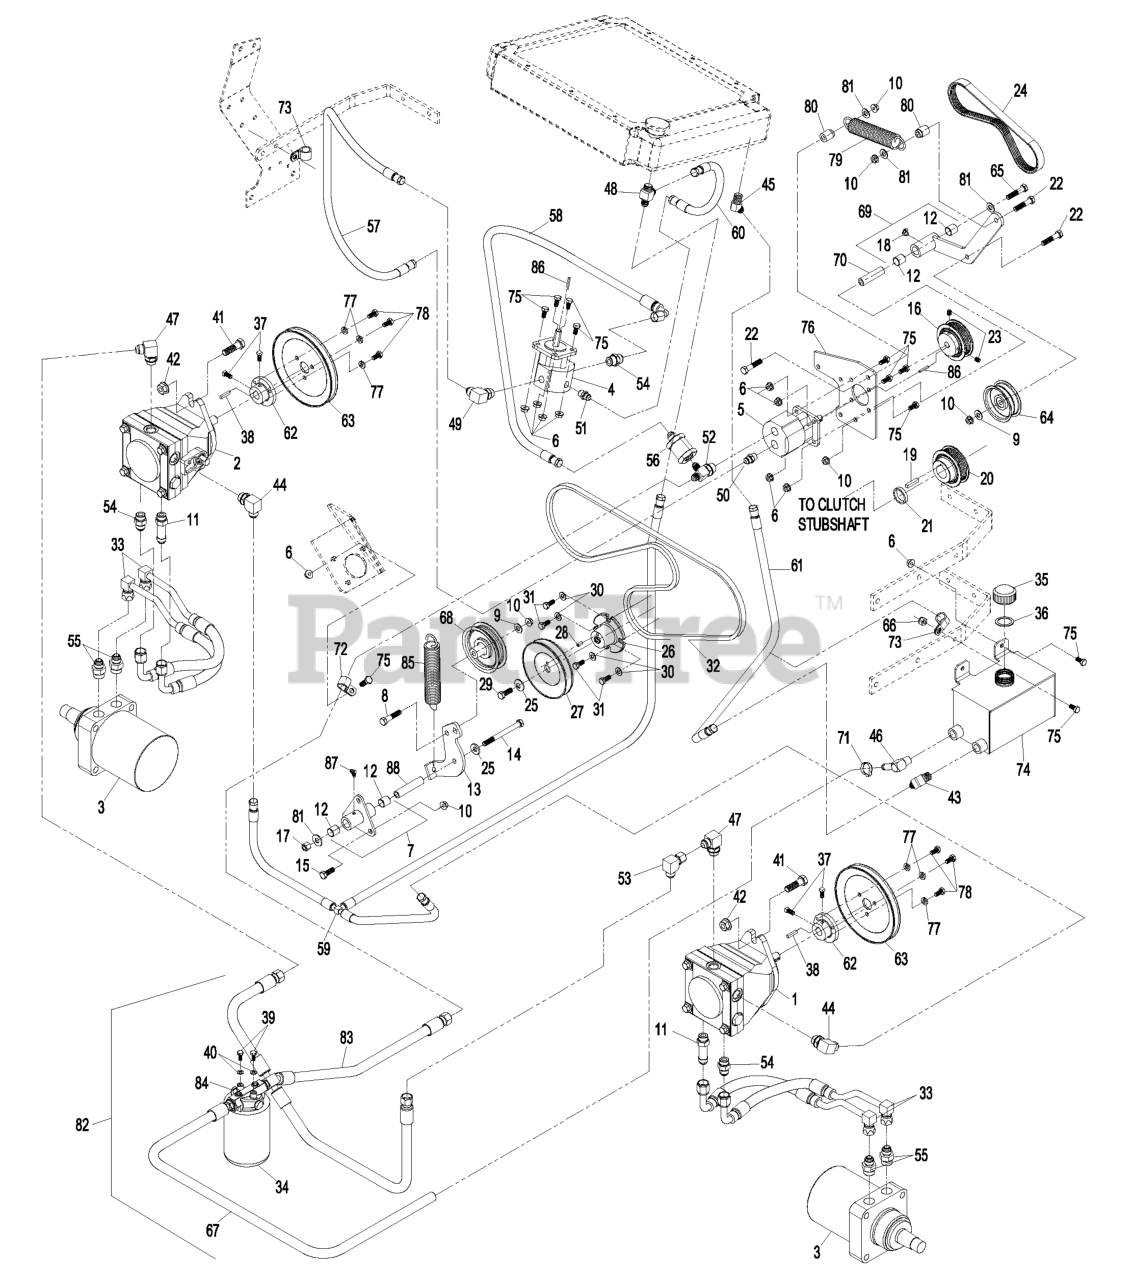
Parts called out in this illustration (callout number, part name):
1	PUMP-HYDRO, LH
2	PUMP-HYDRO, RH
7	PUMP IDLER ASM
8	BOLT-CARR
9	WASHER-FLAT
10	NUT-HHF, WHIZ
11	ADAPTER-STR, LONG
12	SLEEVE-BEARING
13	ARM-TIGHTENER, PUMP
14	SCREW-HH
15	SCREW-HH
16	SHEAVE-5 RIB
17	NUT-LOCK, NI
18	FITTING-GREASE, 90 DEG
19	KEY-SQUARE
20	SHEAVE-5 RIB
21	SPACER-PUMP DRIVE, FAN
22	SCREW-HH
23	SCREW-SET, HSH
24	BELT,POLY-V K 25.38"
25	WASHER-BELLEVILLE
26	HUB-DRIVE, PUMP
27	SHEAVE-ENGINE
28	PIN-ROLL
29	SCREW-HH
30	WASHER-PLAIN
31	SCREW-HH
32	BELT,WRAPPED A-71.26
33	HYD HOSE ASM
34	FILTER,XP HYD 25 MICRON
36	GASKET-CAP, TANK
37	SCREW-SET
39	SCREW-HH
40	WASHER-LOCK
41	SCREW-HH
42	NUT-HHF
43	FITTING-ELBOW, 90 DEG
44	FITTING-ELBOW, 90 DEG
45	FITTING-45 DEG
46	FITTING-90 DEG
47	FITTING-90 DEG
48	FITTING-TEE
49	FITTING-90 DEG
50	FITTING-STRAIGHT
51	FITTING-STRAIGHT
52	FITTING-TEE
53	FITTING-90 DEG
54	FITTING-STRAIGHT
55	FITTING-STRAIGHT
56	FILTER-IN LINE, 50 MICRON
57	AUXILLARY PUMP HOSE ASM
58	HOSE-PRESSURE, HIGH
59	CASE DRAIN HOSE ASM
60	FAN CASE DRAIN HOSE ASM
61	TANK RETURN HOSE ASM
62	HUB-PUMP
63	SHEAVE-PUMP
64	SHEAVE-IDLER
65	SCREW-CARR
66	NUT-LOCK, NI
67	FILTER INLET HOSE ASM
68	IDLER-PUMP
69	ASM,IDLER ARM W/DECALS
70	BUSHING-PIVOT, IDLER
72	CLIP-LOOM
73	CLIP-LOOM
74	KIT,HYD TANK W/DECALS
75	SCREW-HH
76	PLATE-MATING, FAN PUMP
77	WASHER-LOCK
78	SCREW-HH
79	SPRING-EXTENSION
80	SPACER-SPRING, FAN PUMP
81	WASHER-FLAT
82	CHARGE HOSE ASM
83	PUMP INLET HOSE ASM
84	HEAD-FILTER
85	SPRING-EXTENSION
86	KEY-SQUARE
87	FITTING-GREASE
88	BUSHING-TIGHTENER, PIVOT
